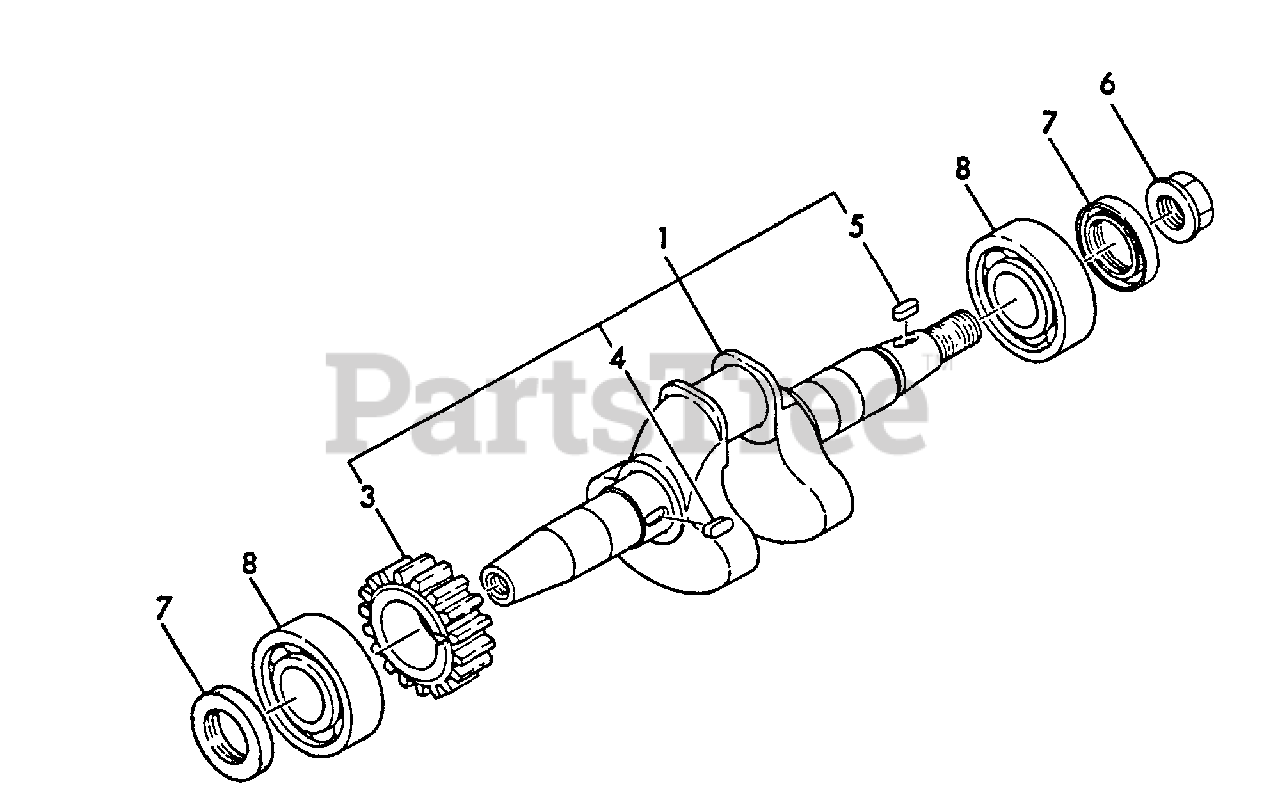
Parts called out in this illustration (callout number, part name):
1	CRANKSHAFT ASSY
3	GEAR, CRANKSHAFT
4	KEY - 4X10
5	KEY - 4X10
6	NUT - 12
7	SEAL, OIL
8	BEARING, BALL - 6204C3
